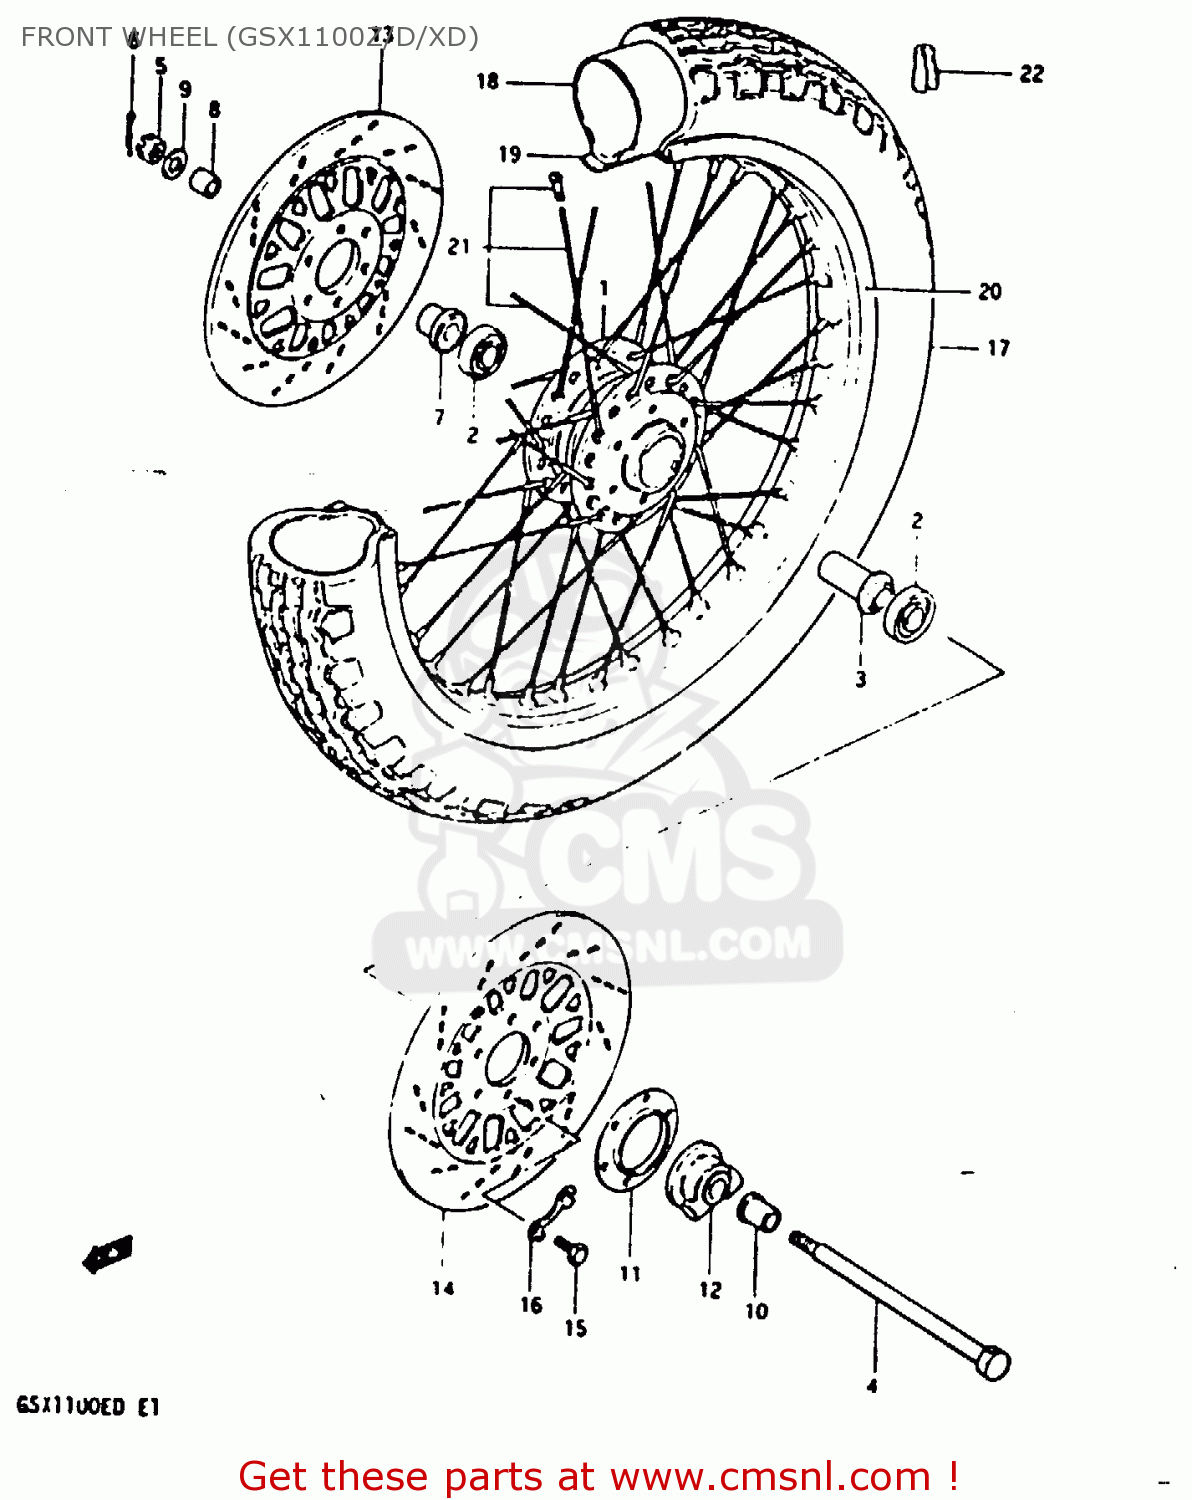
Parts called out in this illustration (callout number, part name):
1	DRUM,FRONT HUB
2	BEARING
3	SPACER,FR HUB BEARING
4	AXLE,FR
5	NUT 12MM
6	COTTER PIN
7	SPACER,FR AXLE,R
8	SPACER,FR AXLE,R
9	WASHER
10	SPACER,FR AXLE,L
11	DUST SEAL,SPEEDOMETER GEAR BOX
12	BOX ASSEMBLY,SPEEDOMETER GEAR
13	DISC,FR BRAKE,R
14	DISC,FR BRAKE,L
15	BOLT(8X25)
16	WASHER
17	TIRE,FRONT
18	TUBE,INNER
19	PROTECTOR,WHEEL,INNER
20	RIM, FRONT WHEEL (1.85-19)
21	SPOKE SET,FRONT
22	BALANCER,WHEEL (B)
